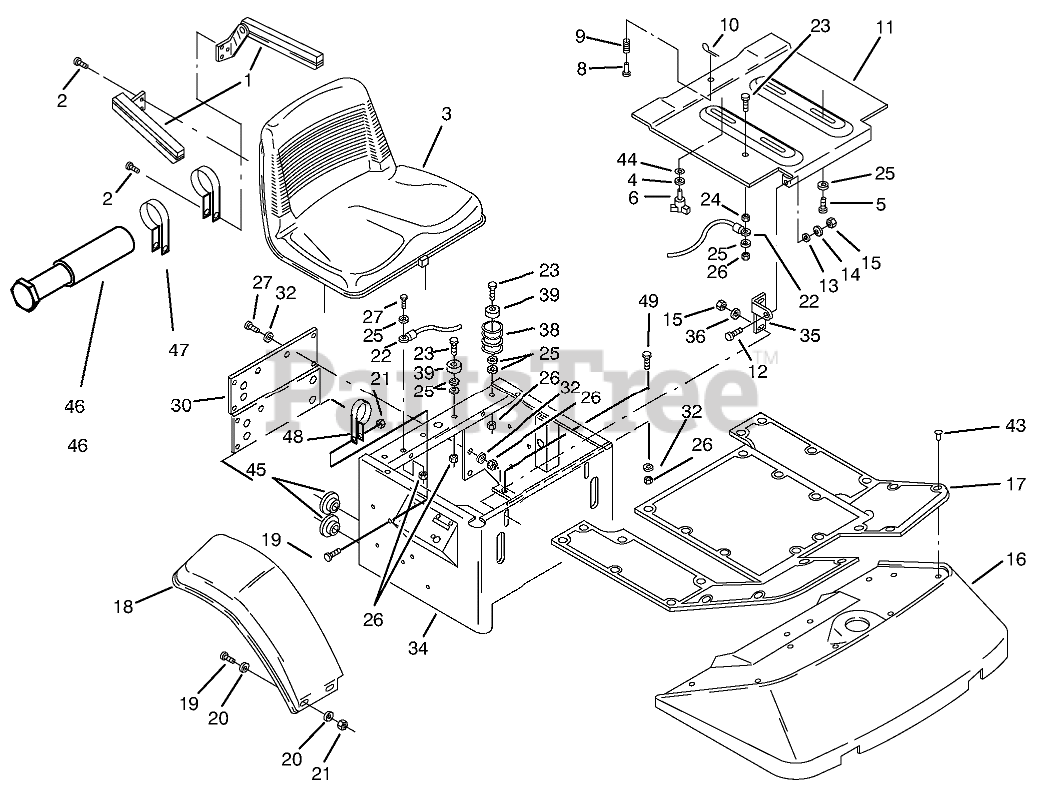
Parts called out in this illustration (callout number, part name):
1	KIT-ARMREST
2	Bolt
3	Seat
4	WASHER-PLAIN
5	BOLT 5/16-18X5/8
9	SPRING-COMPRESSION
10	PIN-COTTER
11	PLATE SEAT PIVOT R
12	BOLT-CARR
13	SPACER
14	WASHER-FLAT
15	NUT-LOCK, NI
16	Floor Pan
17	Black Mat
18	Fender RH
19	SCREW-HH
20	WASHER-FLAT
21	NUT-LOCK, NI
22	Cable
23	SCREW-HH
24	NUT-HEX
25	WASHER-FLAT
26	NUT-LOCK, NI
27	SCREW-HH
30	Cover
32	WASHER-PLAIN
34	SUPPORT-SEAT W A R
35	Seat Pivot Bracket RH
36	WASHER-FLAT
38	Spring-620-Z
39	BUMPER
43	RIVET .25 PLASTIC
44	LOCKWASHER INT EXT
45	BUSHING-NYLON 1.500
46	TUBE-MANUAL
47	CLAMP-R
48	CLAMP-R
49	SCREW-HHF
